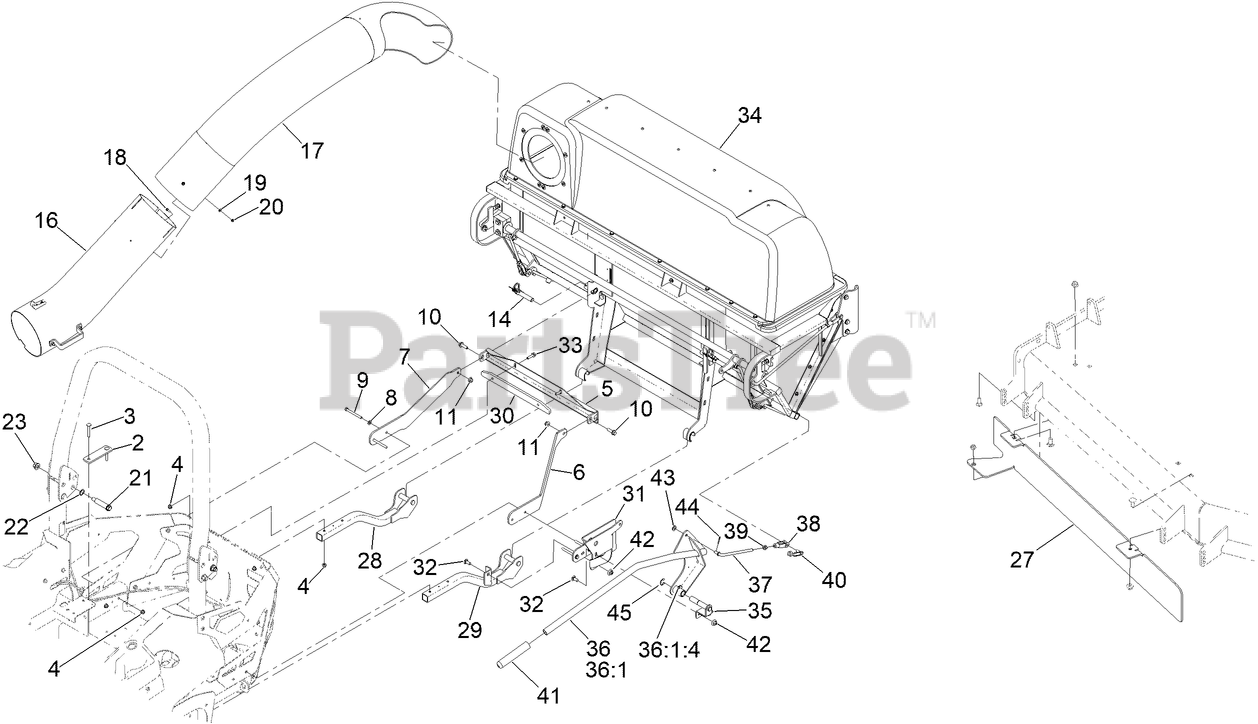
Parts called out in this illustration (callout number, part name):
2	PLATE-BACKER
3	BOLT-CARR
4	NUT-HF, NI
5	SUPPORT-BAGGER, UPPER
6	BRACKET-UPPER, LH
7	BRACKET-UPPER, RH
8	WASHER-PLAIN
9	SCREW-HH
10	SCREW-HHF
11	NUT-HF, NI
14	PIN-MOUNT, BAGGER
16	LOWER TUBE ASM
17	TUBE-UPPER
18	SCREW-HWH
19	WASHER-FLAT
20	NUT-LOCK, NI
21	BOLT-SHOULDER
22	WASHER-WAVE
23	NUT-LOCK
27	BAFFLE-BLOWER [RED]
28	SUPPORT-LOWER, RH [BLACK]
29	SUPPORT-LOWER, LH [BLACK]
30	PLATE-SUPPORT
31	PIVOT MOUNT
32	SCREW-CARR
33	SCREW-HHF
34	DFS ASM
35	PIN-HANDLE
36	HANDLE ASM
36:1	HANDLE ASM
36:1:4	FITTING-GREASE
37	LINK-HANDLE
38	YOKE-LINKAGE, BRAKE
39	NUT-HEX
40	PIN-SPRING, CLEVIS
41	HANDLE-GRIP
42	NUT-FLANGE, NI
43	WASHER-FLAT
44	PIN-COTTER
45	E-RING
